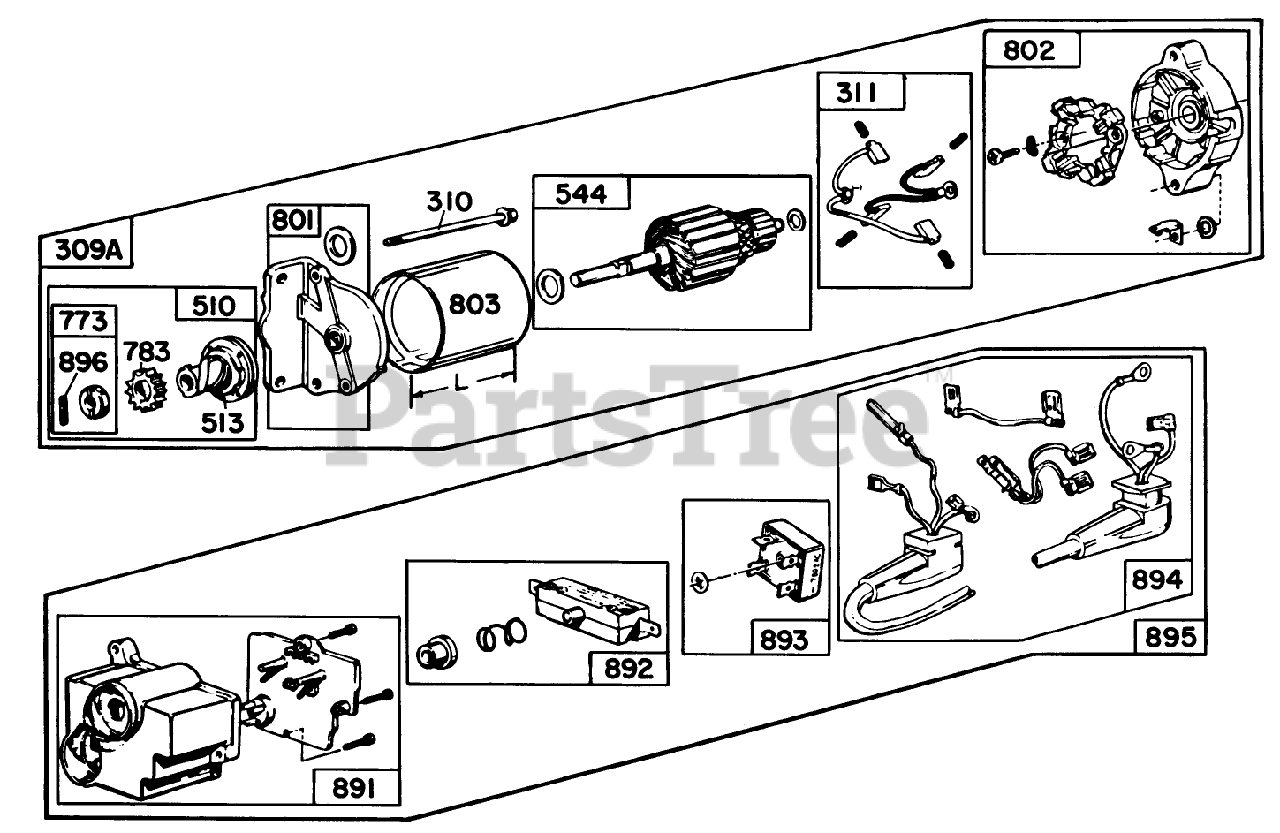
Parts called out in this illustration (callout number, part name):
309	Motor Drive Assembly
310	Thru Bolt Assembly
311	Brush Assembly
510	Drive Assembly
513	Clutch Assembly
544	Armature Assembly
773	Gear-Starter
801	Drive End Cap Assembly
802	Comm. End Cap Assembly
803	Housing Assembly
891	Housing Group
892	Switch Group
893	Rectifier
894	Lead Group
895	Control Group
